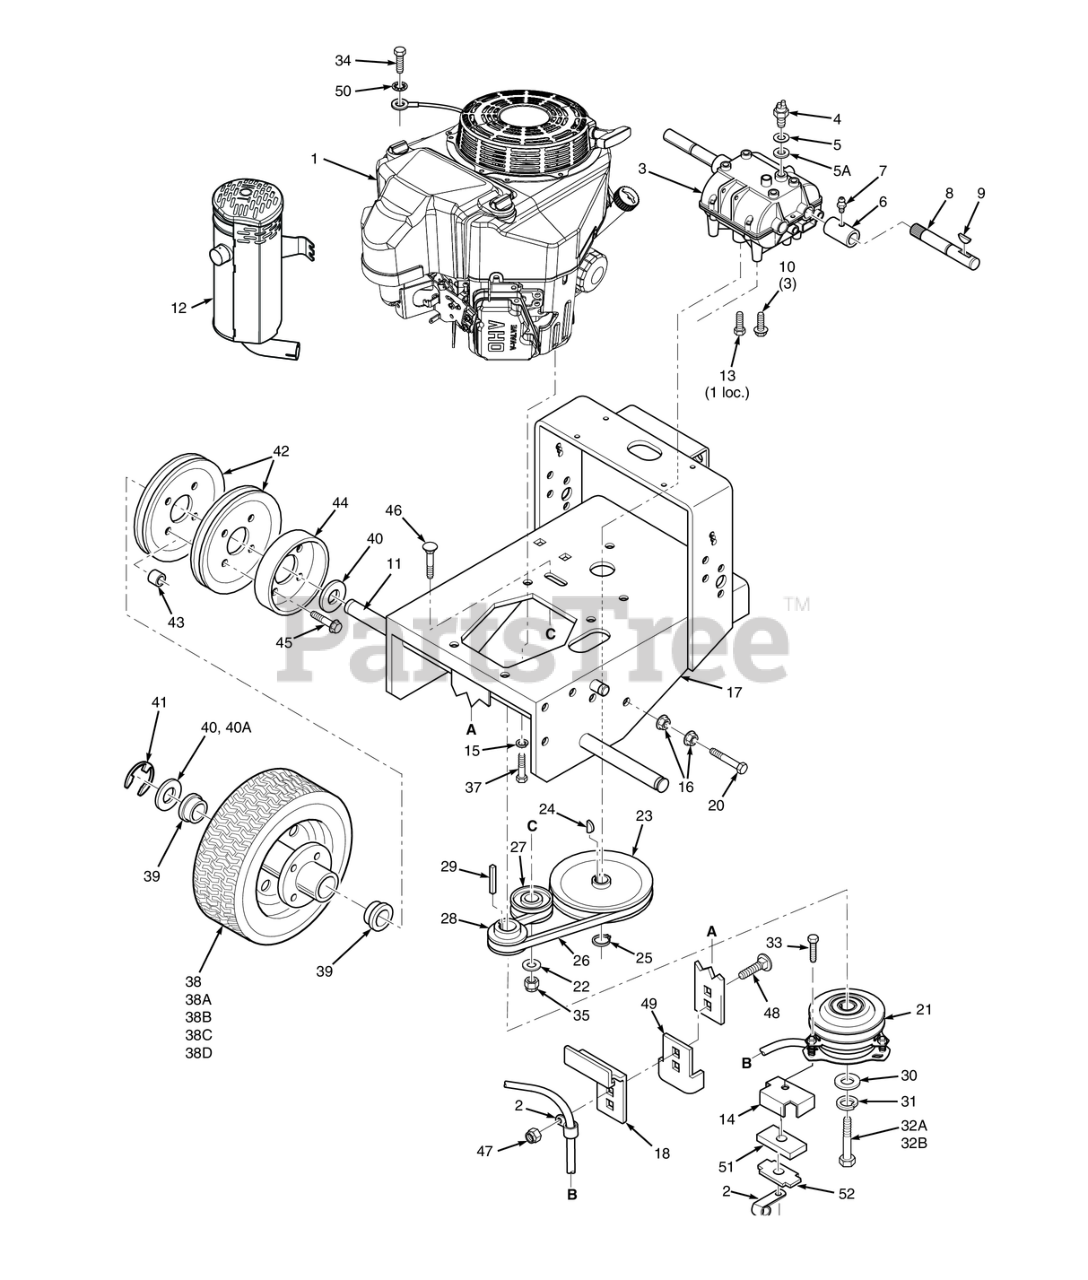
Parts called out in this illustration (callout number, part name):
1	Engine, Kawasaki 14FS (FS481V)
1	Engine, Kawasaki 15FS (FS541V)
2	Clamp, Cable 1/2" I.D.
3	Transmission, 5-speed (Peerless 700-070, 9 tooth spline)
4	SWITCH, TRANSMISSION INTERLOCK N.O.
5	FIBER WASHER - .010
5A	FIBER WASHER - .020
6	Coupler, Jackshaft
7	Greese Fitting, Straight 1/4 - 28
8	Jackshaft (fits SW32,36,48 & 52)
9	KEY, HI PRO #9
10	Capscrew, 5/16-18 x .75 Serrated Flange Hex Head
11	Wheel Axle (SW36,48 & 52)
12	Muffler, Kawasaki (FS481, FS541, FS600)
13	BOLT, SERRATED FLANGE HEX HEAD 5/16-18 X 3/4"
14	Backing Plate, Clutch Stop
15	Lockwasher, 3/8" Spring, Kawasaki FX / FS
16	NUT, 3/8-16 SERRATED FLANGE HEX HEAD
17	Engine Deck (fits SW36,48 & 52)
18	Plate, Clutch Bracket
19	Nut, Serrated Flange 5/16-18 (Right Front Engine Mounting, Briggs and Kohler Only)
20	Capscrew, Hex Head 3/8-16 x 3-3/4"
21	Clutch, Electric (Ogura)
22	Flatwasher, 3/8" Special (.391 x .938 x .105)
23	PULLEY, TRANSMISSION INPUT
24	KEY, WOODRUFF #9, 3/16 X 3/4"
25	RETAINING RING, 5/8 EXT. - BASIC
26	BELT, TRANSMISSION DRIVE
27	Pulley, Idler 3" Dia. - 52"
28	Pulley, Traction Drive
29	KEY, 1/4 X 1/4 X 3/4"
30	Flatwasher, 7/16-.469 x 1.75 x .25 (48, 52)
31	Lockwasher, 7/16� Spring
32A	Bolt, Hex Head 7/16-20 x 2-1/2" (Kohler)
32B	Cpsrw, M10-1.5 x 55 Metric Hex Hd
33	Bolt, Hex Head 5/16-18 x 1-1/2" - Front
34	Bolt, Hex Head M8 - 1.25 x 16 (48V / 52V)
35	HEX NUT, ELASTIC STOP LOCK, 3/8-16
36	Flatwasher, 5/16-.375 x .875 x .083 (35BV & 37BV-EFI)
37	Bolt, Hex Head 3/8-16 x 1-1/4"
38	Wheel Assembly (incl. 38A-38B) (fits SW36,48,52)
38A	Tire, 13 x 6.50-6, 2-ply (fits SW36, 48, 52)
38B	Rim & Bearing Assembly (fits SW36, 48, 52)
39	Wheel Brng. NWC (OD 1.984 - 1.980)
40	Flatwasher, 1" (1.062 x 1.75 x .10)
40A	Flatwasher, 1" (1.062 x 1.50 x .048")
41	Ring, Retaining 1" External "E"
42	PULLEY, WHEEL DRIVE
43	SPACER, WHEEL PULLEY
44	BRAKE DRUM
45	Bolt, Serrated Flange Hex Head 5/16-18 x 1.50"
46	SHORT SQUARE NECK CARRIAGE BOLT, 3/8-16 X 2"
47	HEX NUT, ELASTIC STOP LOCK, 5/16-18
48	Bolt, Carriage 5/16-18x1" (large frame units only)
49	Plate, Clutch Anti-Rotation
50	Lockwasher, 5/16" Ext. Tooth (Kohler x1)
51	Rubber Pad, Clutch Stop
52	Plate, backing Clutch Pad
